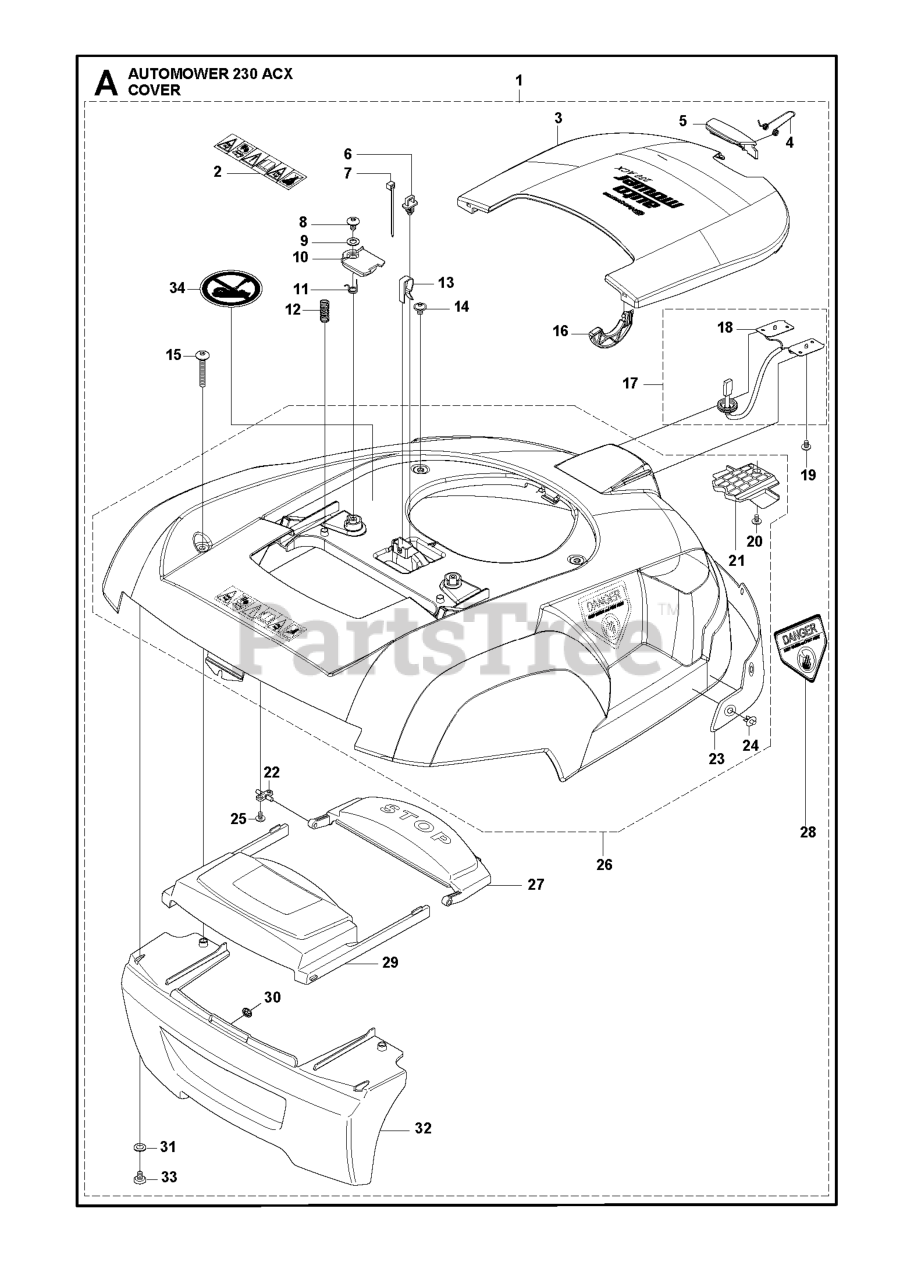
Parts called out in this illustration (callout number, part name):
2	LABEL WARNING
3	COVER 230 ACX
5	HEIGHT ADJ. COVER LATCH
6	BRACKET FOR BAND
8	SCREW SILVER 10MM
13	CLIP RETAINER
15	SCREW IHPANM
17	CABLE ASSY
18	THIN PLATE
19	SCREW WHITE 6MM
20	SCREW 12MM
25	SCREW SILVER 10MM
26	BODY KIT INCL NEW BODY
28	LABEL, DANGER
32	BUMPER, COVER
33	SCREW 14MM
34	LABEL WARNING KIT 10 PCS
